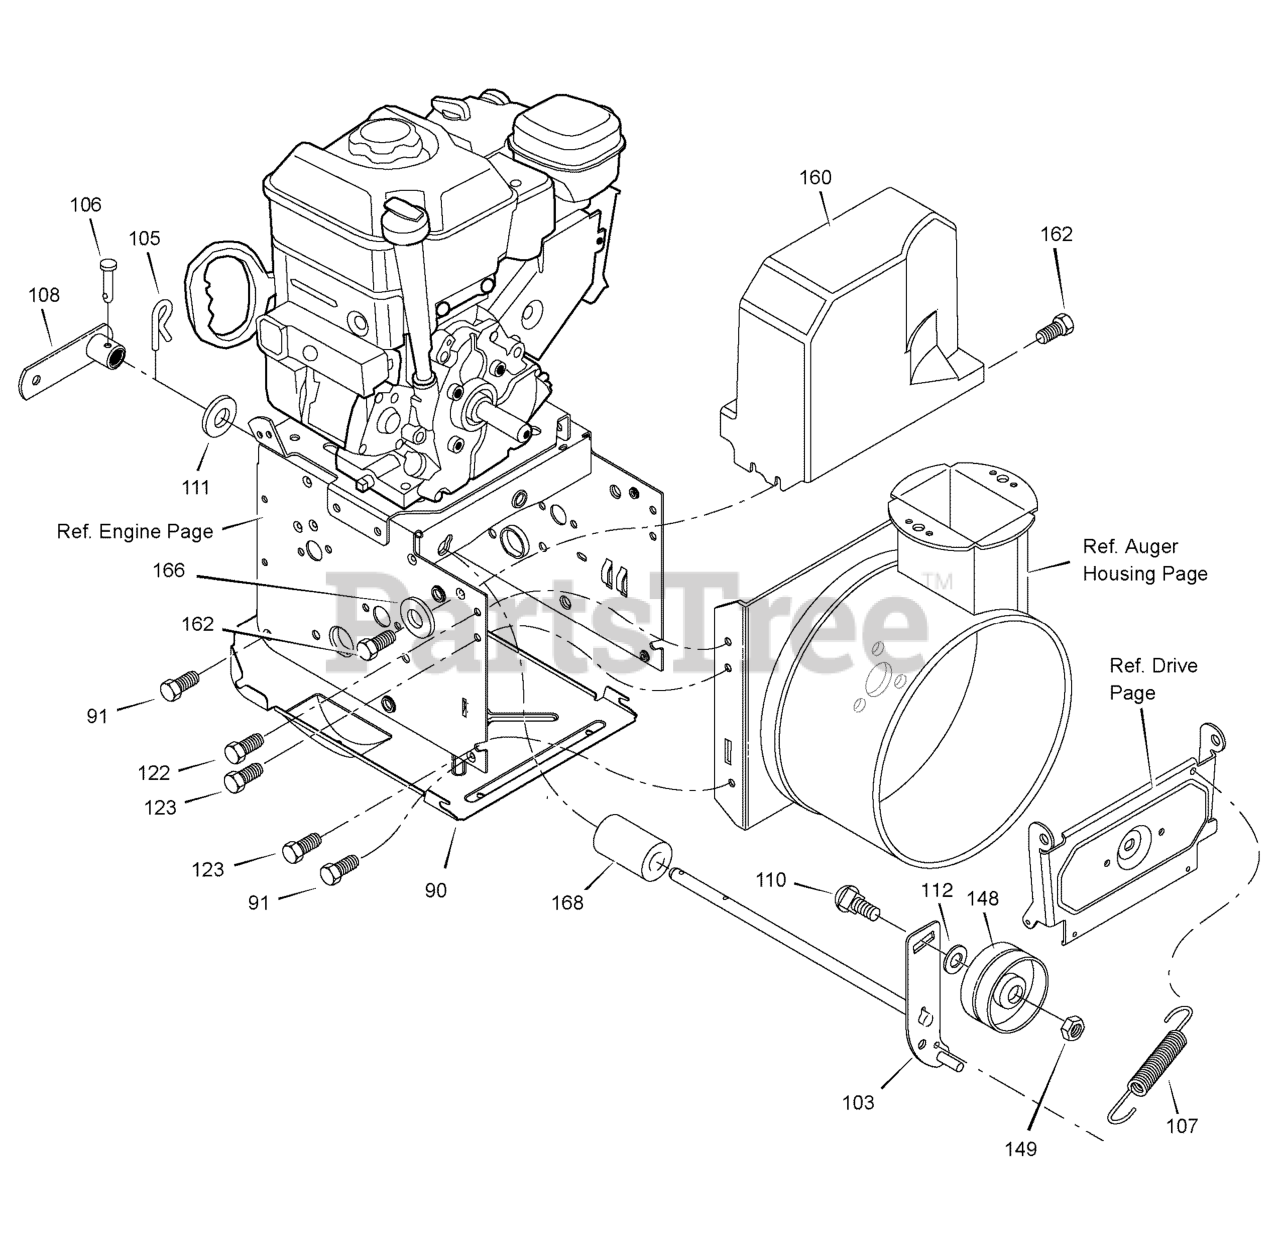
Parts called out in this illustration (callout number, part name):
90	COVER, BOTTOM
91	SCREW, 1/4-20 X 0.63
103	IDLER ASSEMBLY, AUGER
105	PIN, HAIR .38DIA X 1.64LG
106	PIN, CLEVIS 3/16" DIA
107	SPRING, TENSION
108	SPRING ATTACH, ASSEMBLY
110	BOLT, 3/8-16 X 1.25 CARRIAGE
111	WASHER, FLAT
122	SCREW, TAP 5/16-18 X 0.50
123	SCREW, TAP 5/16-18 X 0.75
148	PULLEY, IDLER
149	NUT, JAM 3/8-16
160	COVER, BELT
162	SCREW, TAP
166	WASHER, FLAT
168	SPACER, AUGER BRACKET
